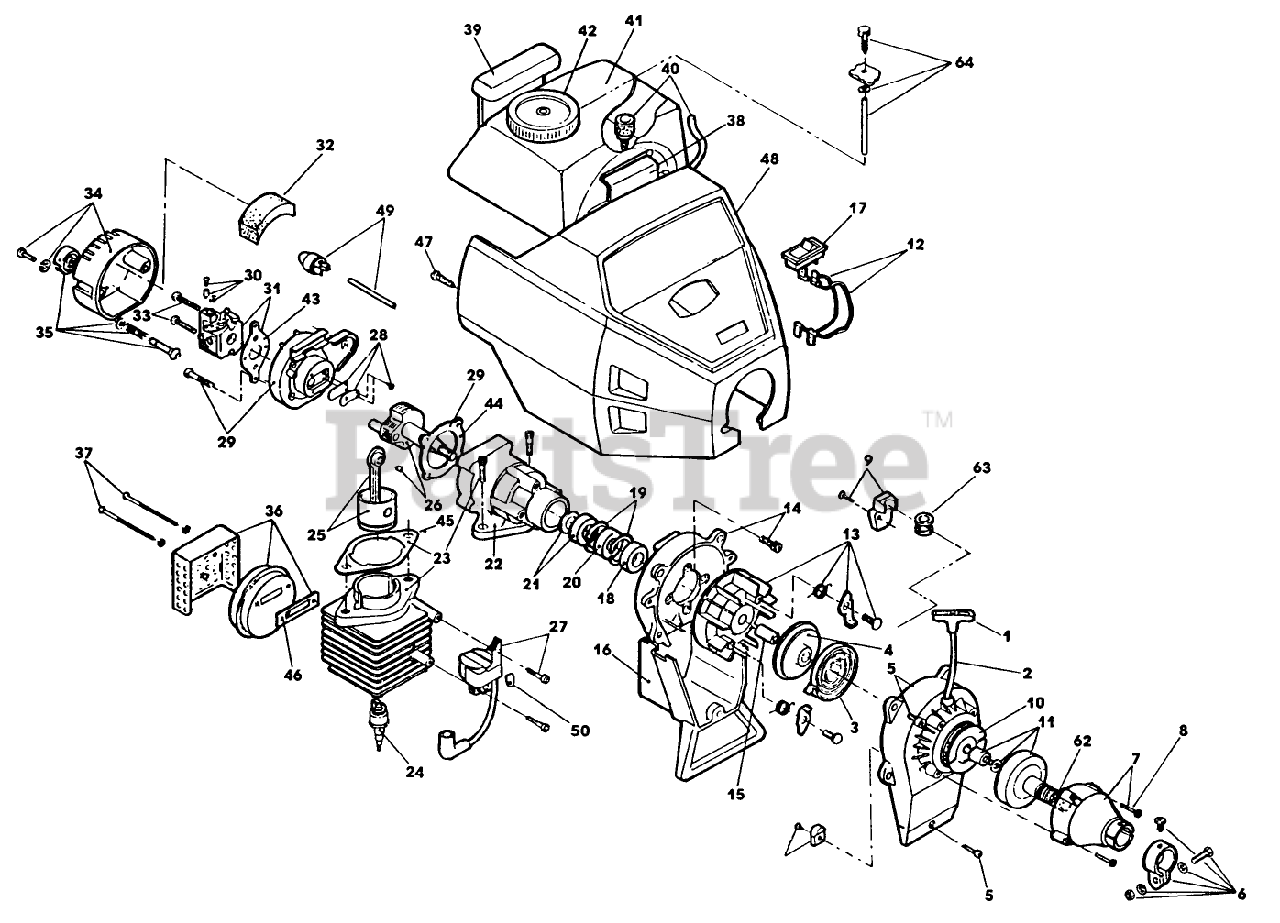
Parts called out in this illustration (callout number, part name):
3	RECOIL SPRING
6	CLAMP ASM - UPPER
14	SHROUD ASM
18	OUTER BEARING
21	INNER BEARING ASM
24	SPARK PLUG
30	THROTTLE ADJ ASM
37	MTNG BOLT ASM 2 PCS = 1
38	FRONT MOUNTING PAD
39	REAR MOUNTING PAD
40	FUEL LINE ASM
43	CARB.GASKET
62	COMPRESSION SPRING
64	FUEL RETURN LINE ASM
